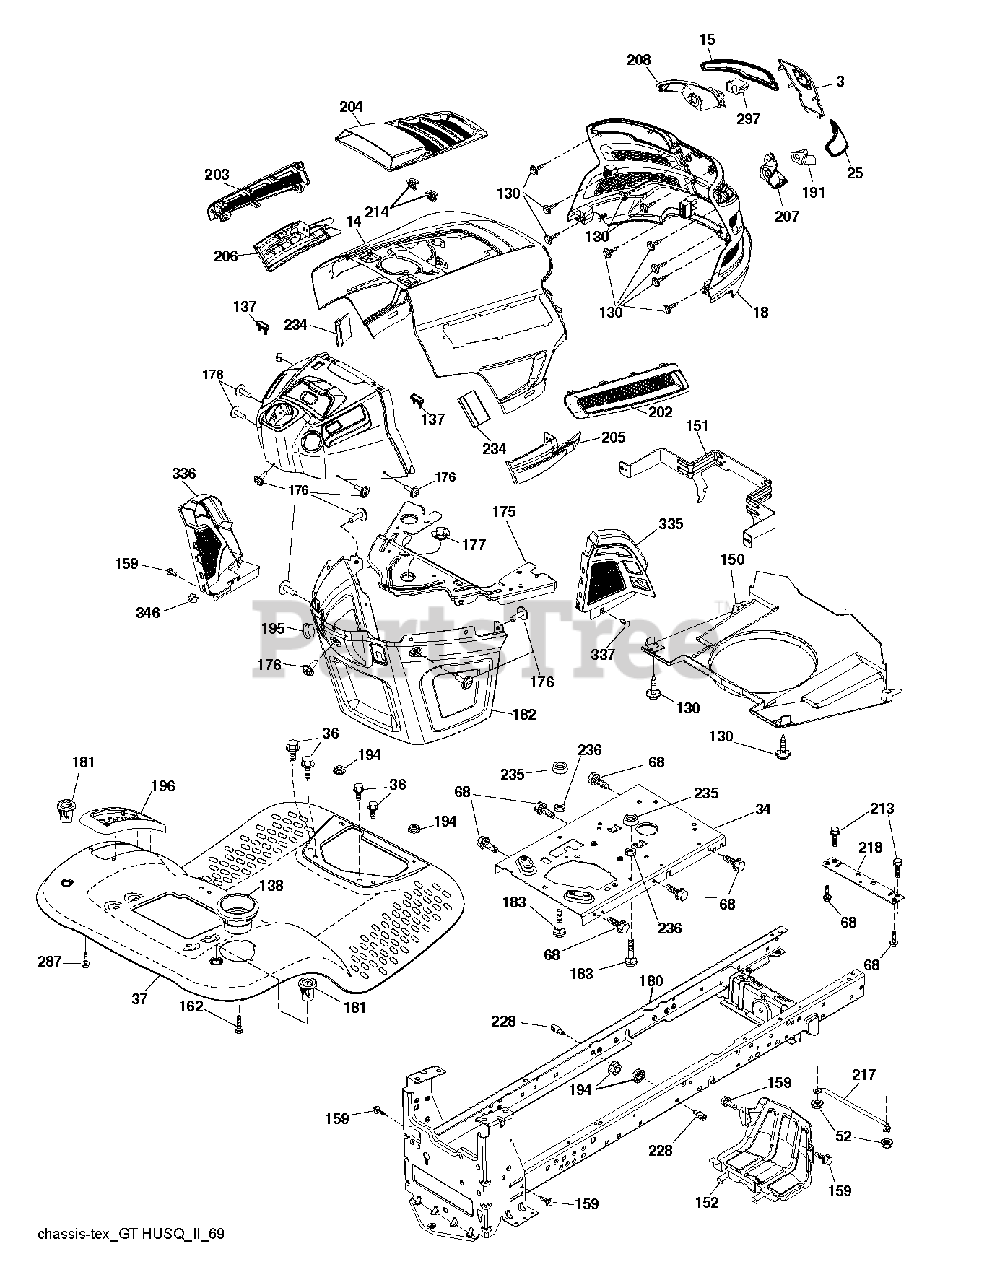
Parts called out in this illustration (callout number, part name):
3	APPLIQUE.SUBASM.GT.HUSQ.II
5	RP.DASH.UPP.GT2.SM.MC.CHOKE
14	HOOD.ASM.HUSQVARNA.GT.TEX.422
15	LENS.HEADLIGHT.LH.GTII.2011
18	GRILLE.SUBASM.GT.HUSQ.II
25	LENS.HEADLIGHT.RH.GTII.2011
34	PLATE.ENGINE.WELDED.CHASSIS
36	SCREW 5/16"
37	FENDER
52	LOCKNUT
68	SCREW LT
130	SCREW.#10 X 0.750.BOS
137	BUMPER DASH
138	CUPHOLDER.TL.TEX.BLACK
150	AIR DUCT.GTV2(1.66"RING HEIGHT
151	BRACKET.PIVOT.HOOD.GT.HUSQ.II
152	SHIELD.BROWNING.PNT.GT.V2
159	SCREW, 3/8-16X3/4
162	SCREW.HI-LO.CONSOLE
175	PLATE.CROSSMEMBER.HUSQ
176	SCREW.#10-24X5/8.RN.QU
177	BUSHING, STEERING
180	CHASS.WLDMNT.TL.12GA/2P.48/54
181	BUSHING.MNT.FEND.CRGO.TEX.49
182	DASH.LOWER.COMMON.12V.ADAPTOR
183	BOLT.5/16-18X1-1/4 FULL THD
191	INSERT.REFLECTIVE.RH.HUSQ.GTII
194	NUT LOCK HEX FLANGE 5/16-18
195	PLUG.HOLE.DASH.LOWER.12V.BLK
196	DECKLFT.CONSOL FULL ASSM GREY
202	VENT.SIDE.RH.GT.HUSQ.II.
203	VENT.SIDE.LH.GT.HUSQ.II.498
204	VENT.TOP.HUSQ.GT2
205	SIDE.TRIM.RH.GT.HUSQ.II
206	SIDE.TRIM.LH.GT.HUSQ.II.GRAY
207	BEZEL LIGHT.RH.GT.II.MYLAR
208	BEZEL LIGHT.LH.GT.II.MYLAR
213	BOLT
214	CLIP.RETAINER.TINNER.
217	ROD.PIVOT.HOOD
218	X-PIECE.HOOD.STOP.NON/
228	STUD.FASTNER.W/ANTI-ROTATE
234	BUMPER.HOOD.TEX.HUSQVARNA
235	SPACER FENDER
236	NUT.CENTERLOCK.5/16-
287	SCREW 1/4X20
297	INSERT.REFLECTIVE.LH.HUSQ.GTII
335	COVER.RH.CLOSE.OUT.BLACK
336	COVER-LH.LOWER.DASH.GT2.BLACK
337	CLIP.XMAS.TREE.ITW.2622-00
346	CLIP,INSULATOR
